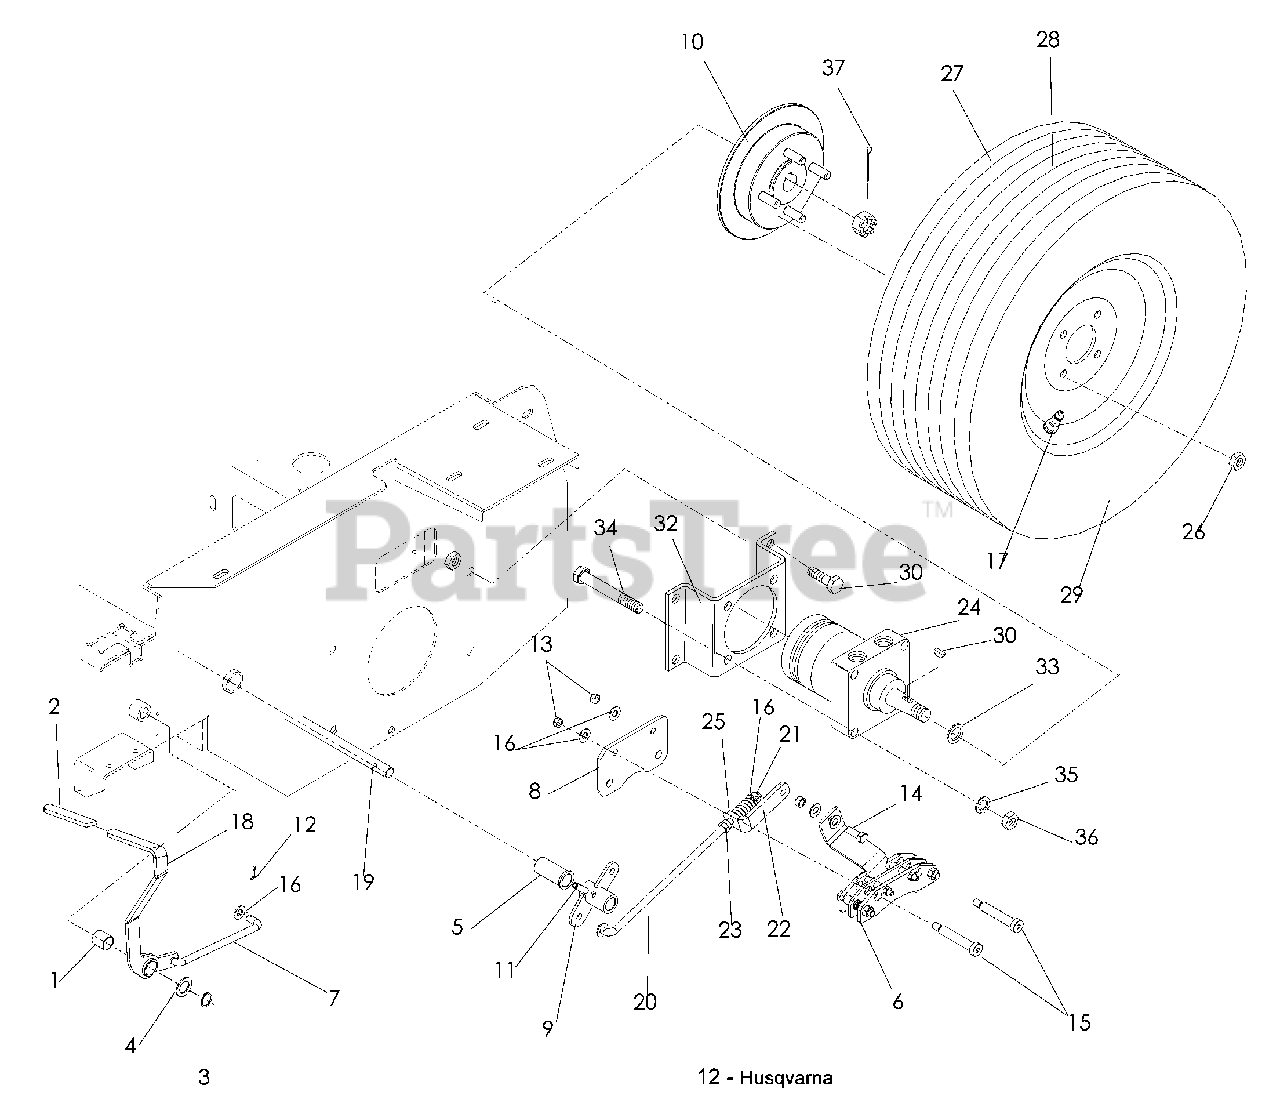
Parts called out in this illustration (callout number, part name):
3	RING, RETAINING 7/8
4	BUSHING, MACHINE
5	BUSHING, POLYMER ¾ x 2
7	LINKAGE, BRAKE
8	PLATE, BRAKE
9	BELLCRANK, BRAKE
11	PIN, ROLL, 5/16" DIA.
12	PIN, COTTER 3/32 x ¾
13	NUT 3/8-16 JAM NYLOC
14	HCS 3/8-16 x 1
15	SB 3/8-16 x 2½ SKT HD
16	WASHER 3/8 SAE FLT
17	VALVE STEM
18	BRAKE LEVER
19	SHAFT, CROSS
20	LINKAGE, REAR BRAKE
21	NUT 3/8-24 CENTERLOCK
22	BRACKET, L
23	NUT 3/8-24 JAM
24	WHEEL MOTOR, TJ
26	NUT ½-20 HEX LUG
27	TIRE, COMPLETE
28	TIRE, 23 x 9.5-12
29	RIM, OFFSET 1"
30	KEY, WOODRUFF
31	NUT ½-13 HEX NYLOC
32	STANDOFF, WHEEL MOTOR
33	BUSHING, MACHINE, 1"
34	HCS ½-13 x 2¾
35	LOCKWASHER ½
36	NUT ½-13 HEX
37	PIN, COTTER
